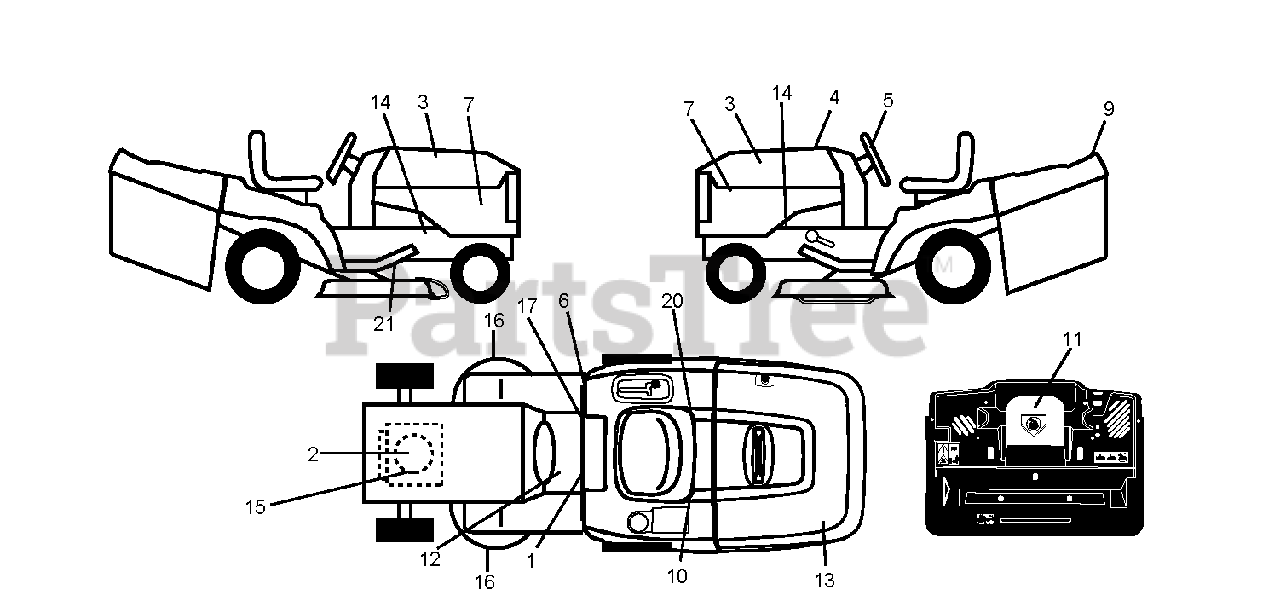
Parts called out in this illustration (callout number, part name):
10	DECAL BTRY SYMBOLS
11	DECAL.INTERNATIONL.CUTFINGER
16	DECAL.INTERNATIONL.CUTFINGER
17	DECAL PARK BRAKE
20	DECAL.BYPASS.FENDER.CRD.LT.YT
